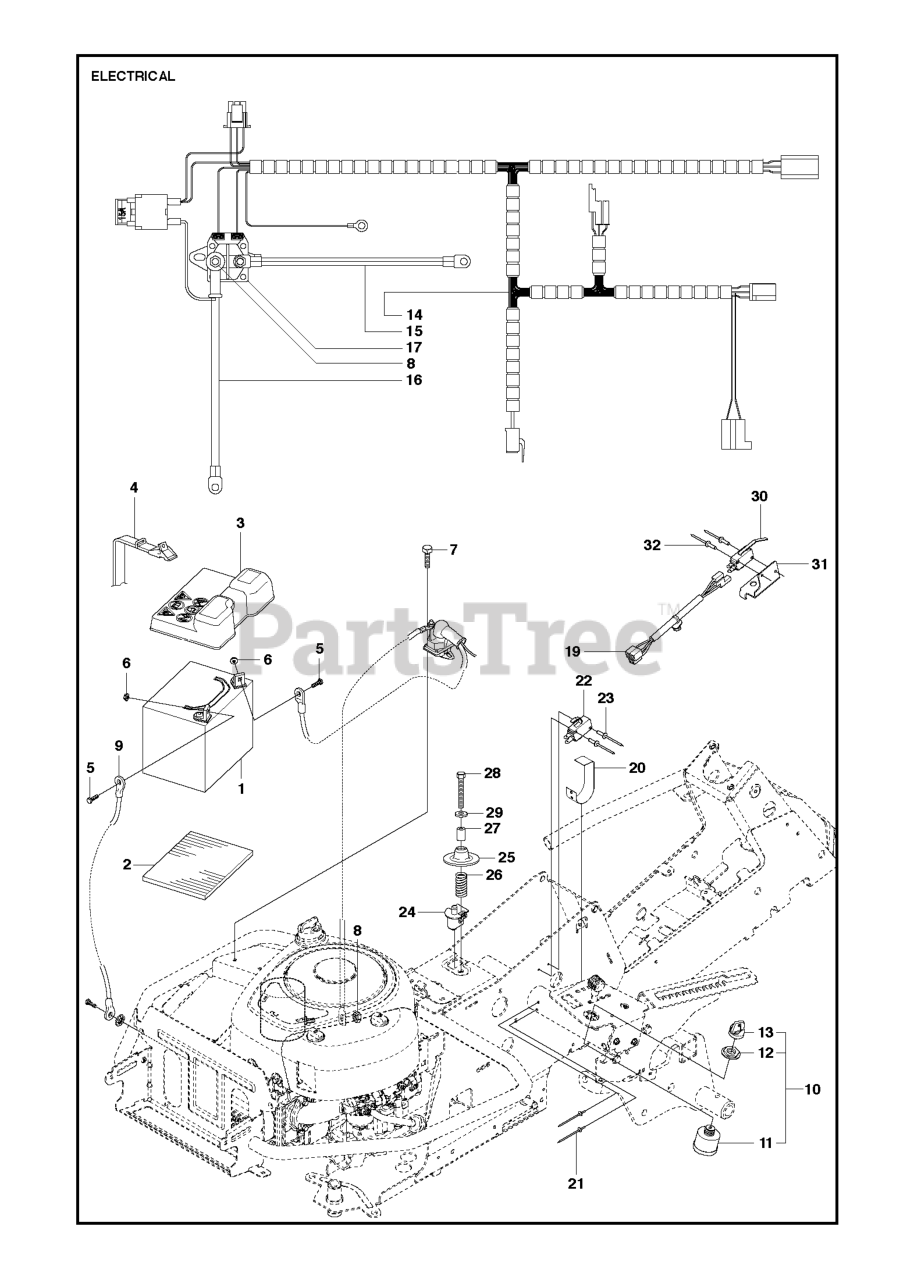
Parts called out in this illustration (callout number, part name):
5	SCREW EHHM
10	IGNITION SWITCH
11	IGNITION SWITCH
13	IGNITION KEY
15	CABLE
19	WIRING
27	SPACER TUBE
28	SCREW
29	WASHER BRB 8.4X17
30	MICRO SWITCH
